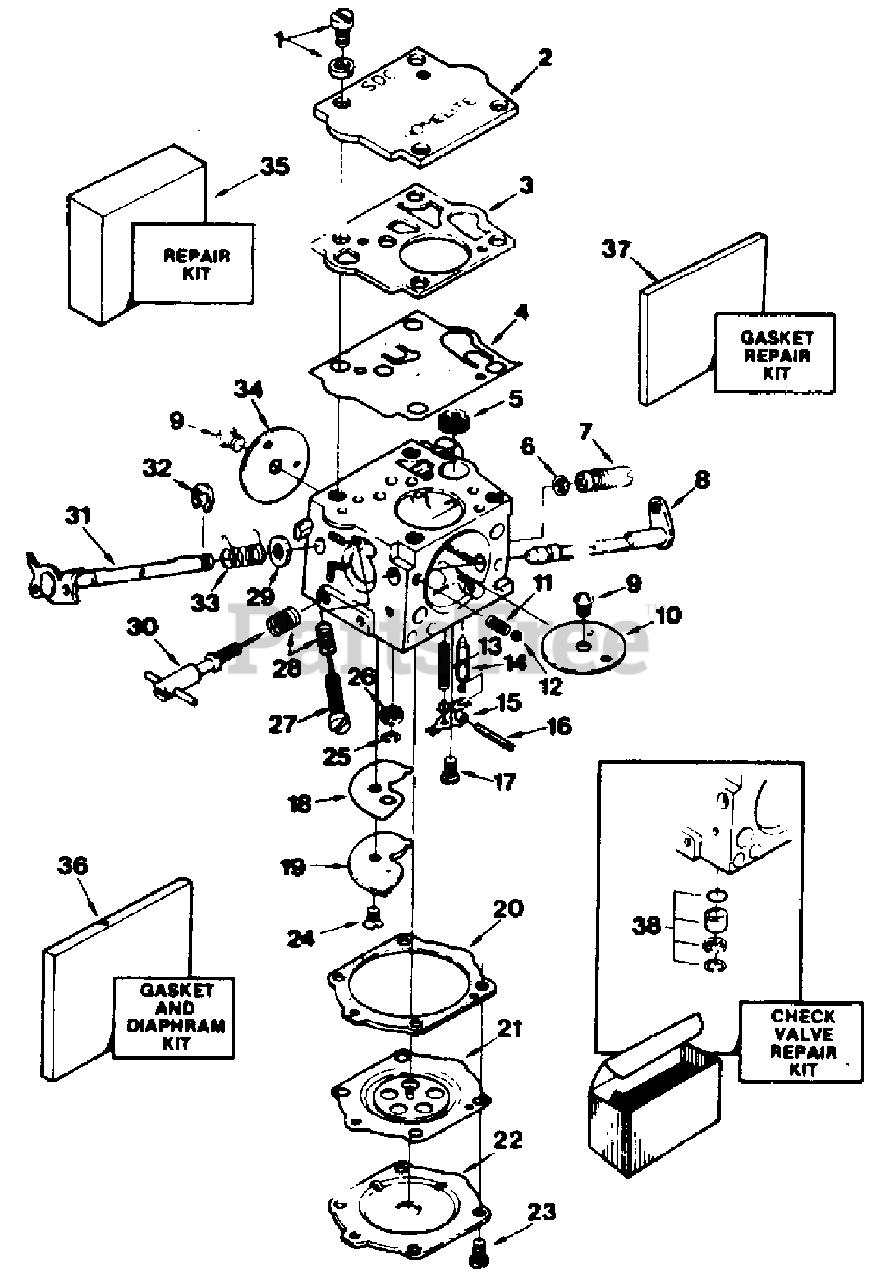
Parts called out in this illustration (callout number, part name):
1	SCREW- Pump cover
2	COVER- Fuel pump
3	GASKET- Pump
4	DIAPHRAGM- Pump
5	SCREEN- Inlet
6	WASHER- Check valve
7	KIT- Governor check valve
8	SHAFT ASSEMBLY- Choke
9	SCREW- Valve
10	VALVE- Choke
11	SPRING- Choke friction
12	BALL- Choke friction
13	SPRING- Metering lever (SDC-60)
14	VALVE- Inlet needle
15	LEVER- Metering
16	PIN- Metering lever
17	SCREW- Metering lever pin
18	GASKET- Circuit plate
19	PLATE- Circuit (SDC-60)
20	GASKET- Metering
21	DIAPHRAGM ASSEMBLY- Metering
22	COVER- Metering diaphragm
23	SCREW ASSEMBLY
24	SCREW- Circuit plate (SDC-60)
25	RING- Screen retaining
26	SCREEN- Check valve
27	SCREW- Idle adjustment
28	SPRING- Needle adjustment
29	WASHER- Nylon
30	NEEDLE ASSEMBLY- Idle
31	SHAFT ASSEMBLY- Throttle
32	RING- Retaining
33	SPRING- Throttle return
34	VALVE- Throttle
35	KIT- Repair (SDC-60)
36	KIT- Gasket & diaphragm (SDC-60)
37	GASKET SET
38	KIT- Check valve
